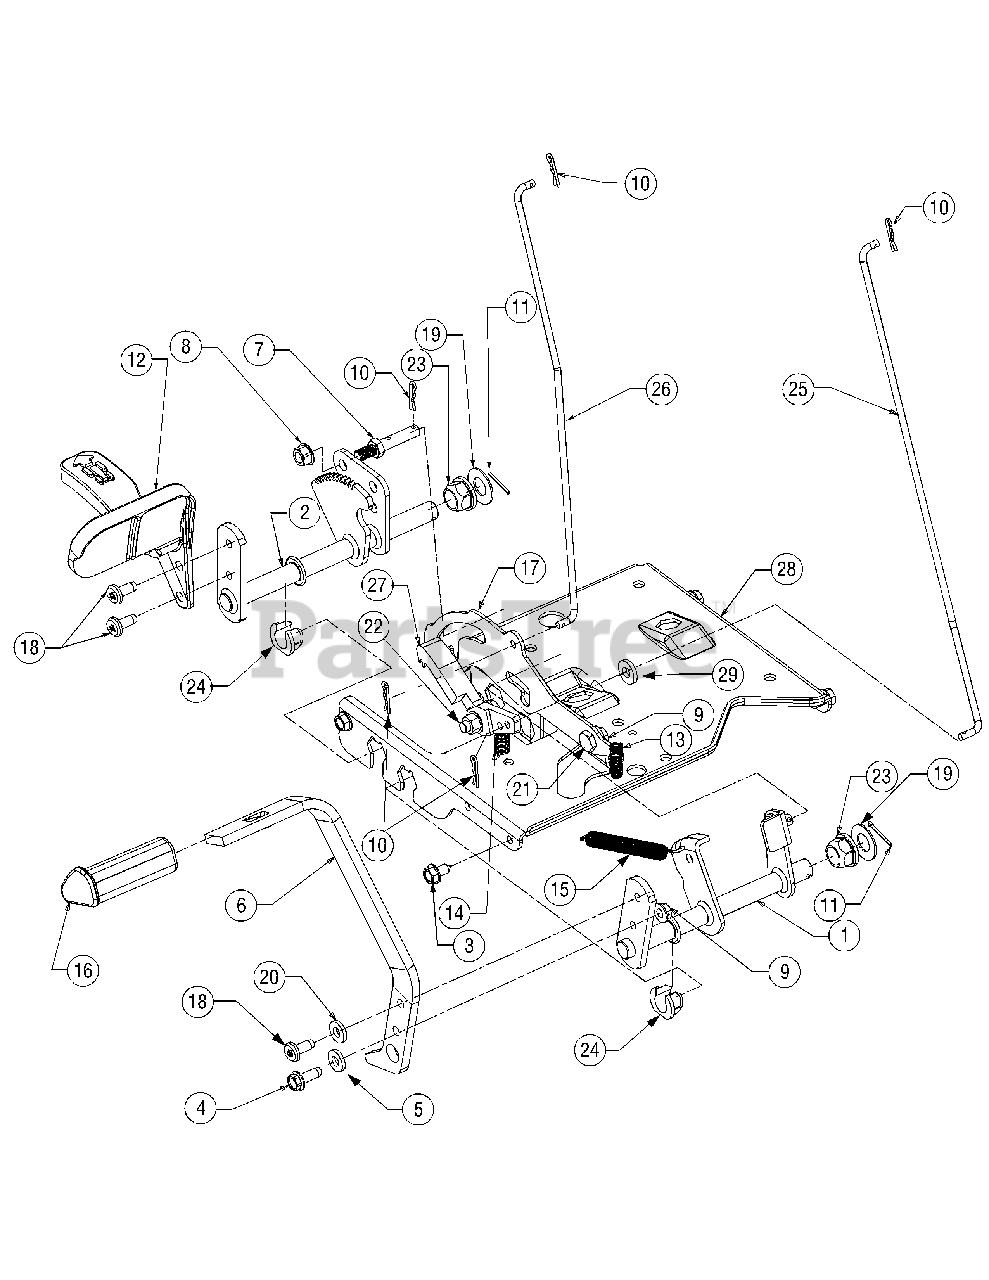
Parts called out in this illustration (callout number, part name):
4	Screw, Self-tapping, 5/16-18,
5	Washer, Lock, 5/16
8	Nut, Nylon Lock, 3/8-16
9	Nut, Flange Lock, 5/16-18, Gr5
10	Pin, Cotter, .072 Dia. x 1.13 Lg
11	Pin, Cotter, 3/32, 1.0
13	Spring, Compression, .405 x 1.17
14	Spring, Extension, .50 OD x 1.41
15	Spring, Extension, .50 Dia x 6.37
16	Pad, Brake, Control
17	Bracket, Lockout, Hydro
18	Screw, Torx Hd. Tapp. 5/16-18 x
19	Washer, Flat .64 ID x 1.24 x .06
20	Washer, Flat, .344 x .750 x .120
21	Shoulder, Screw .437
22	Shoulder, Screw 3/8-16
23	Bearing, Hex Flange
24	Bearing, Hex Flange, .628 ID, Split
25	Rod, Control, Cruise
26	Rod, Control, Brake Lock
27	Latch, Cruise
29	Lock Washer,.406 x.875 x.059
